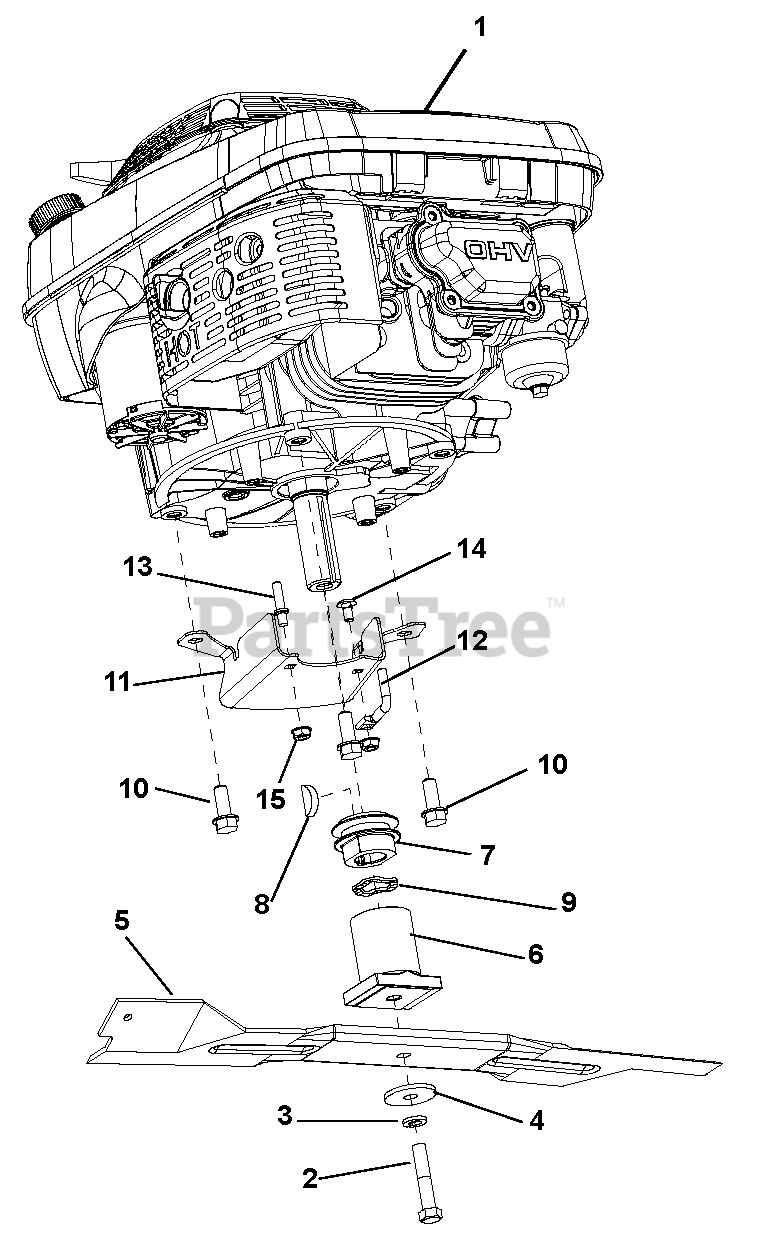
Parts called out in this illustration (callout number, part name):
1	Engine, KAWI FJ180V Commercial (911270)
2	Bolt, Hex .38-24 x 2.00 Grade 8
3	Washer, Locking .38 x .094 Regular
4	Washer, Flat, Steel .39 x 1.5 x .125
5	21" Mower Blade
6	Adapter, CE Blade (911270)
7	Pulley, Sintered Iron LM (911270)
8	Key, Woodruff .156 x .625 x .25 SAE6 G106750 (911270)
9	Washer, Wave .885 x 1.311 x .125 (911270)
10	Screw, Tapping .38-16 x 1.00 Hex Washer Head Thread (911270)
11	Channel, XD21 Front Belt
12	Finger, Belt
13	Finger, Belt
14	Bolt, Round Head Square Neck .25-20 x .50
15	Nut, Locking, Flange .250-20
